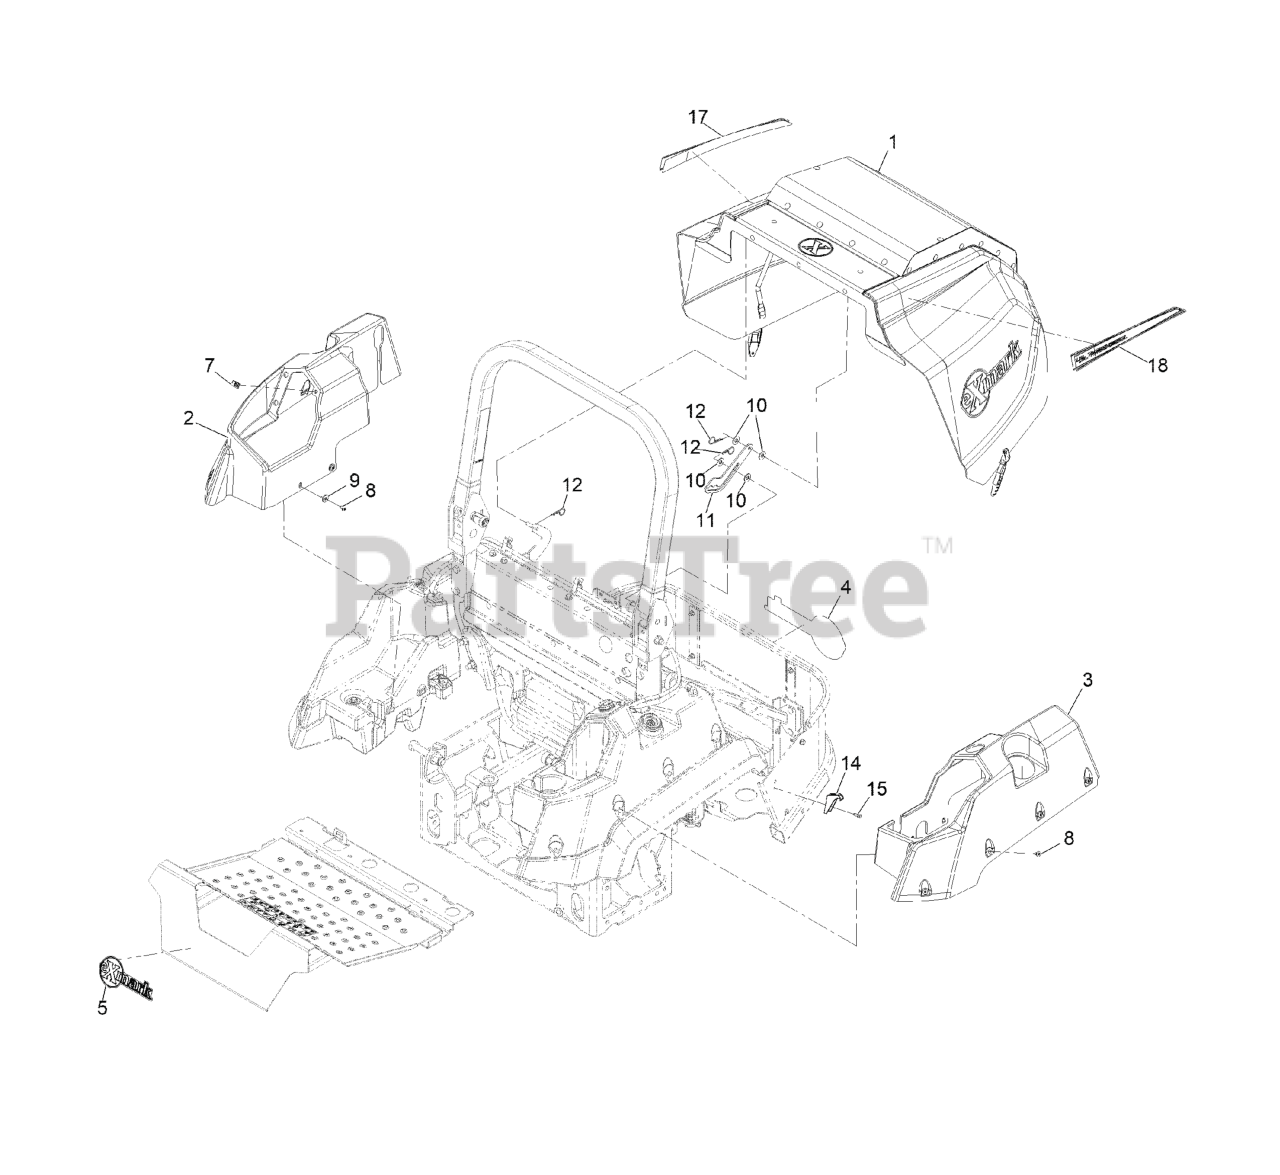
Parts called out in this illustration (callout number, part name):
1	ASM, HOOD LZSD
2	COVER-TANK, RH
3	COVER-TANK, LH
4	DECAL-EXMARK
5	DECAL-EXMARK
8	SCREW-TORX
9	WASHER-FLAT
10	WASHER-FLAT
11	PROP-HOOD
12	PIN-COTTER, HAIR
14	LATCH-CATCH
15	SCREW-HWH
17	DECAL-TURBO DIESEL-RH
18	DECAL-TURBO DIESEL-LH
